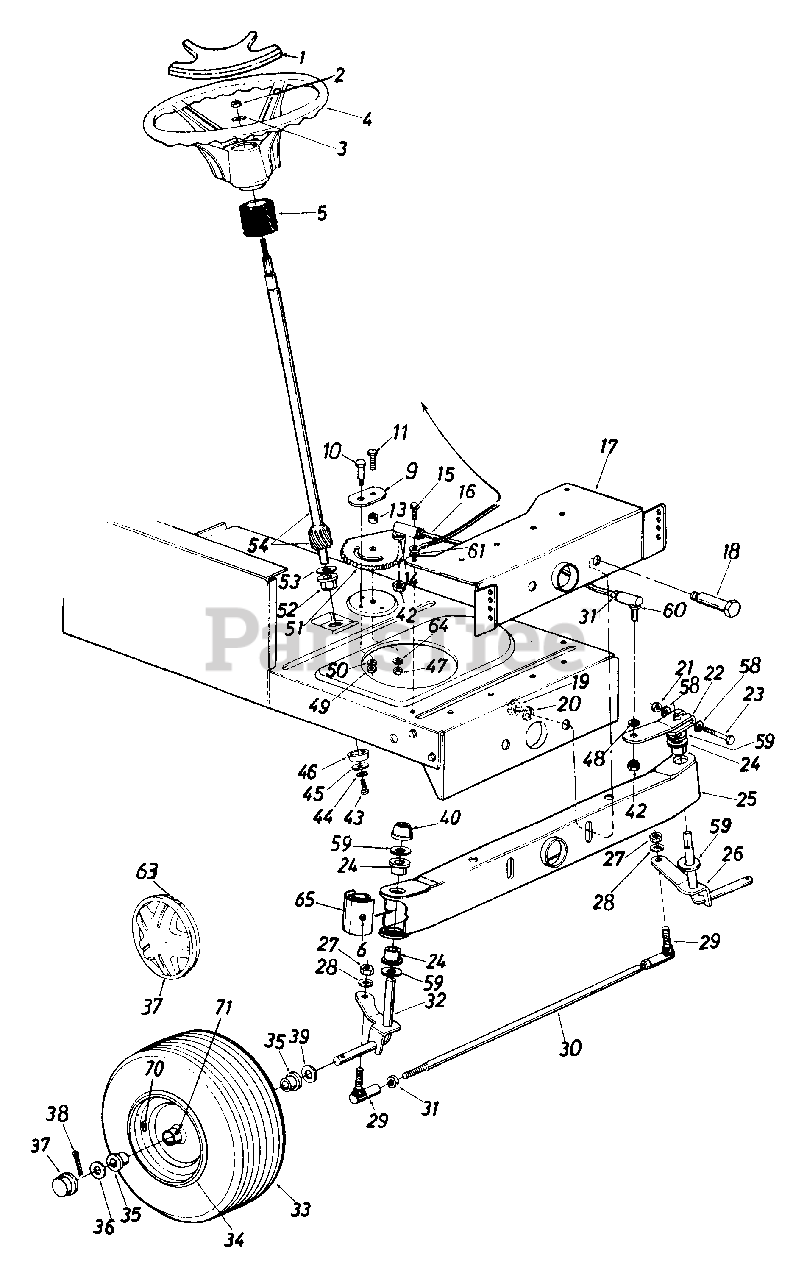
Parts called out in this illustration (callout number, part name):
1	Steering Wheel Cap
2	Hex L-Nut 5/16-24 Thd.
3	Belleville Wash. .345" I.D.
4	Steering Wheel
5	Steering Bellow
6	Grease Fitting
9	Retainer Plate
10	Shoulder Bolt .437" Dia. x .35 Lg. 5/16-18 Thd.
11	Hex Bolt 3/8-24 x 1.0" Lg. (Grade 5)
13	Spacer .380" I.D. x .625" O.D. x .227
15	Hex Wash. Hd. Self-Tap Scr.
16	Steering Drag Link
17	Front Pivot Brkt.
18	Shoulder Bolt .498" Dia. x 2.04 Lg. 3/8-16 Thd.
19	Hex Nut 3/8-16 Thd.
20	L-Wash. 3/8" I.D.
21	Hex L-Nut 5/16-24 Thd.
22	Steering Arm Front Axle
23	Hex Bolt 5/16-24 x 2.00" Lg. (Grade 5)
24	Hex Flg. Brg. .632 I.D.
26	Front Axle Ass'y. - L.H.
27	Hex Nut 3/8-24 Thd.
28	L-Wash. 3/8" I.D.
29	Ball Joint 3/8-24 Thd.
31	Hex Jam Nut 3/8-24 Thd.
32	Front Axle Ass'y. - R.H.
36	Fl-Wash. .635 I.D. x 1.59" O.D.
37	Hub Cap
38	Cotter Pin 1/8" Dia. x 1.25"
39	Fl-Wash. .640" I.D. x 1.24" O.D.
40	Push Cap 5/8" Dia. Rod
42	Hex Jam Nut 3/8-24 Thd.
43	Hex L-Bolt 5/16-18 x .62"
44	L-Wash. 5/16" I.D.
45	Fl-Wash. .33" I.D. x 1.25" O.D.
46	Spacer (Plastic)
47	Hex Cent. L-Nut 3/8-24 Thd.
48	L-Wash. 3/8" I.D.
49	Hex Cent. L-Nut 5/16-18 Thd.
50	L-Wash. 5/16" I.D.
51	Steering Gear Segment
52	Hex Flg. Brg. .634 I.D.
53	Fl-Wash. (Hardened)
54	Steering Shaft
58	Wave-Wash. .32" I.D. x .62" O.D.
59	Fl-Wash. (Hardened)
60	Drag Link Ball Joint 3/8-24 Thd.
61	Ext. L-Wash. 5/16" I.D.
63	Spring Clip
64	Bell-Wash. .39" I.D. x 1.38" O.D.
65	Pivot Bar End Cap
70	Air Valve
71	Grease Fitting
